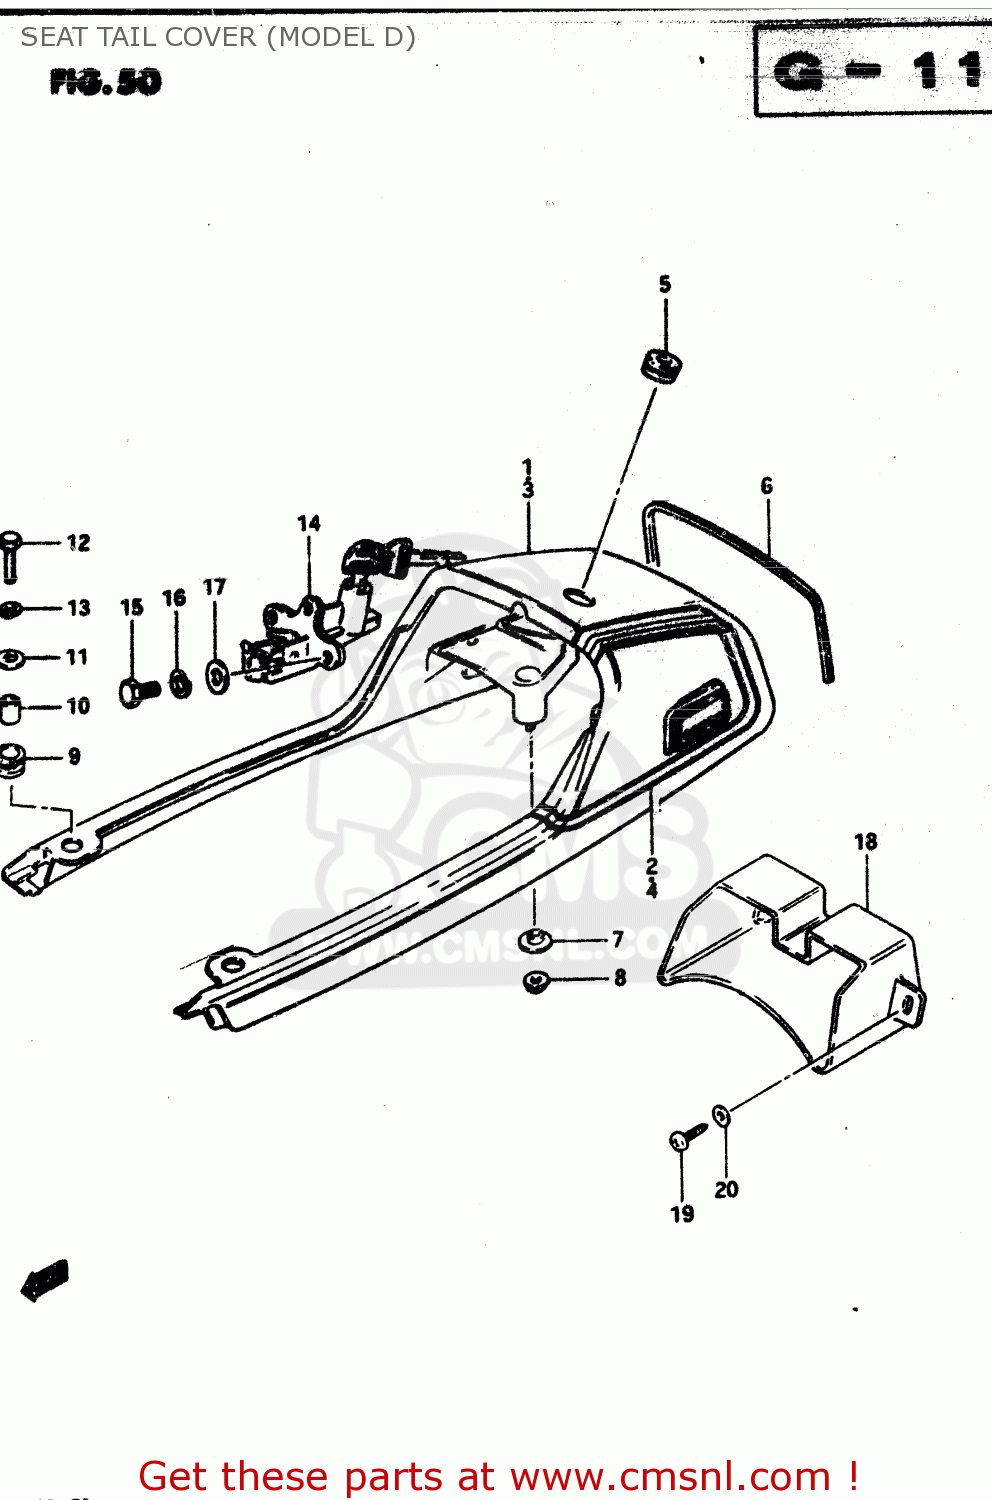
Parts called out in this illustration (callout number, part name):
1	COVER, SEAT TAIL
2	TAPE SET
3	COVER, SEAT TAIL
4	TAPE SET
5	GROMMET,SEAT LOCK HOLE
6	MOLDING,SEAT TAIL COVER
7	WASHER
8	NUT 6MM
9	CUSHION
10	SPACER (7X10X12)
11	WASHER (6.5X24X1.6)
12	BOLT
13	LOCK WASHER
14	LOCK SET,SEAT
15	BOLT
16	LOCK WASHER
17	WASHER
18	BOX, SEAT TAIL
19	SCREW
20	WASHER
